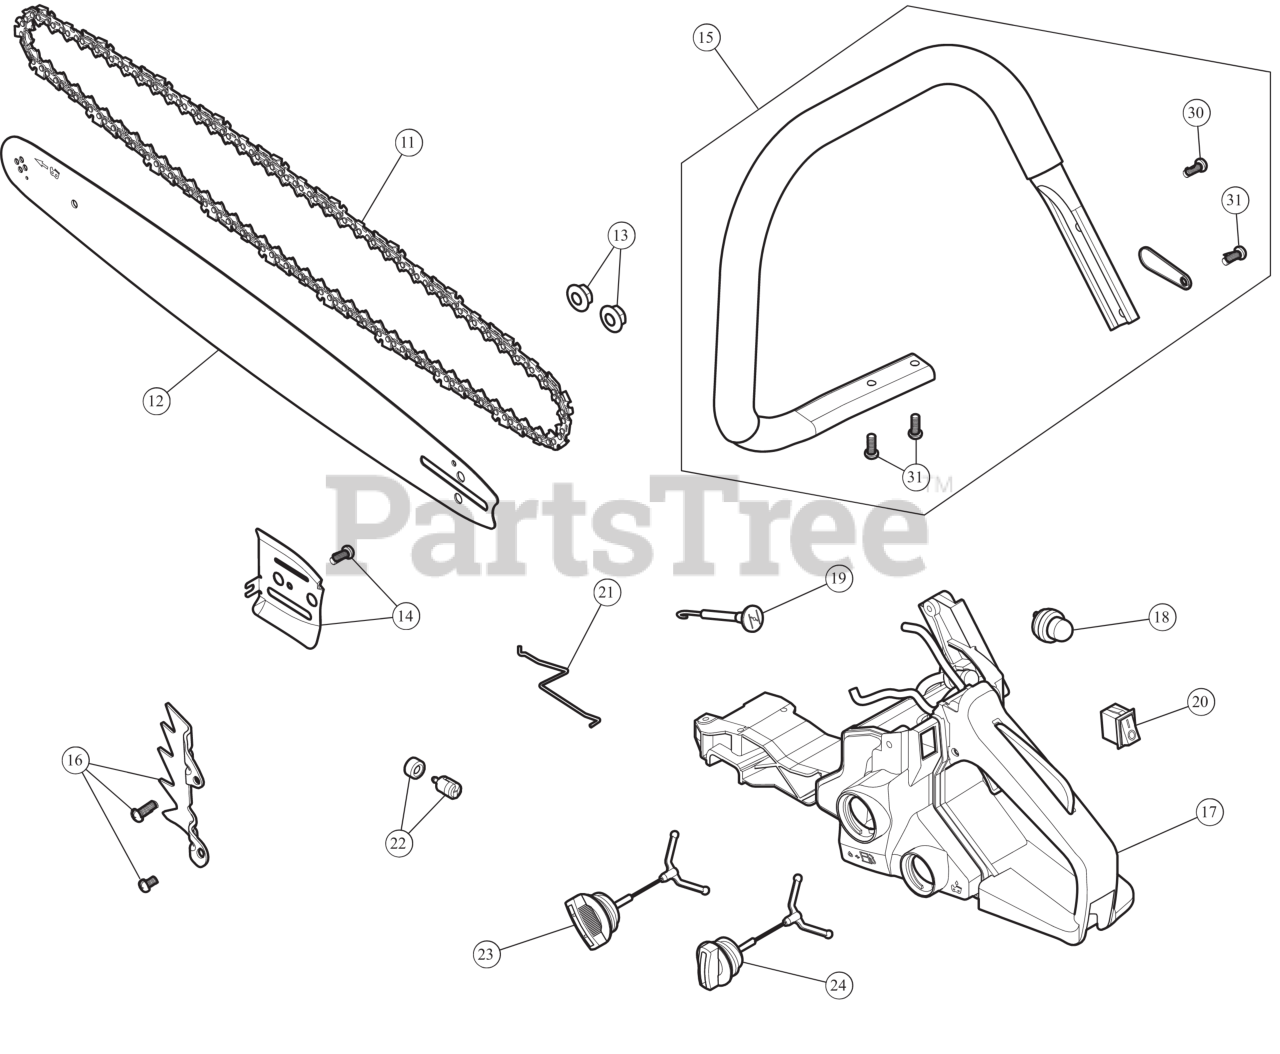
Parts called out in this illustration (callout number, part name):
11	16" CHAIN
12	16" GUIDE BAR
13	BAR NUT M8
14	BAR PLATE
15	CHAINSAW HANDLE
16	SPIKE PLATE
18	PRIMER BULB
19	CHOKE LEVER
20	STOP SWITCH
21	THROTTLE ROD
22	FUEL FILTER
23	FUEL CAP
24	OIL CAP
